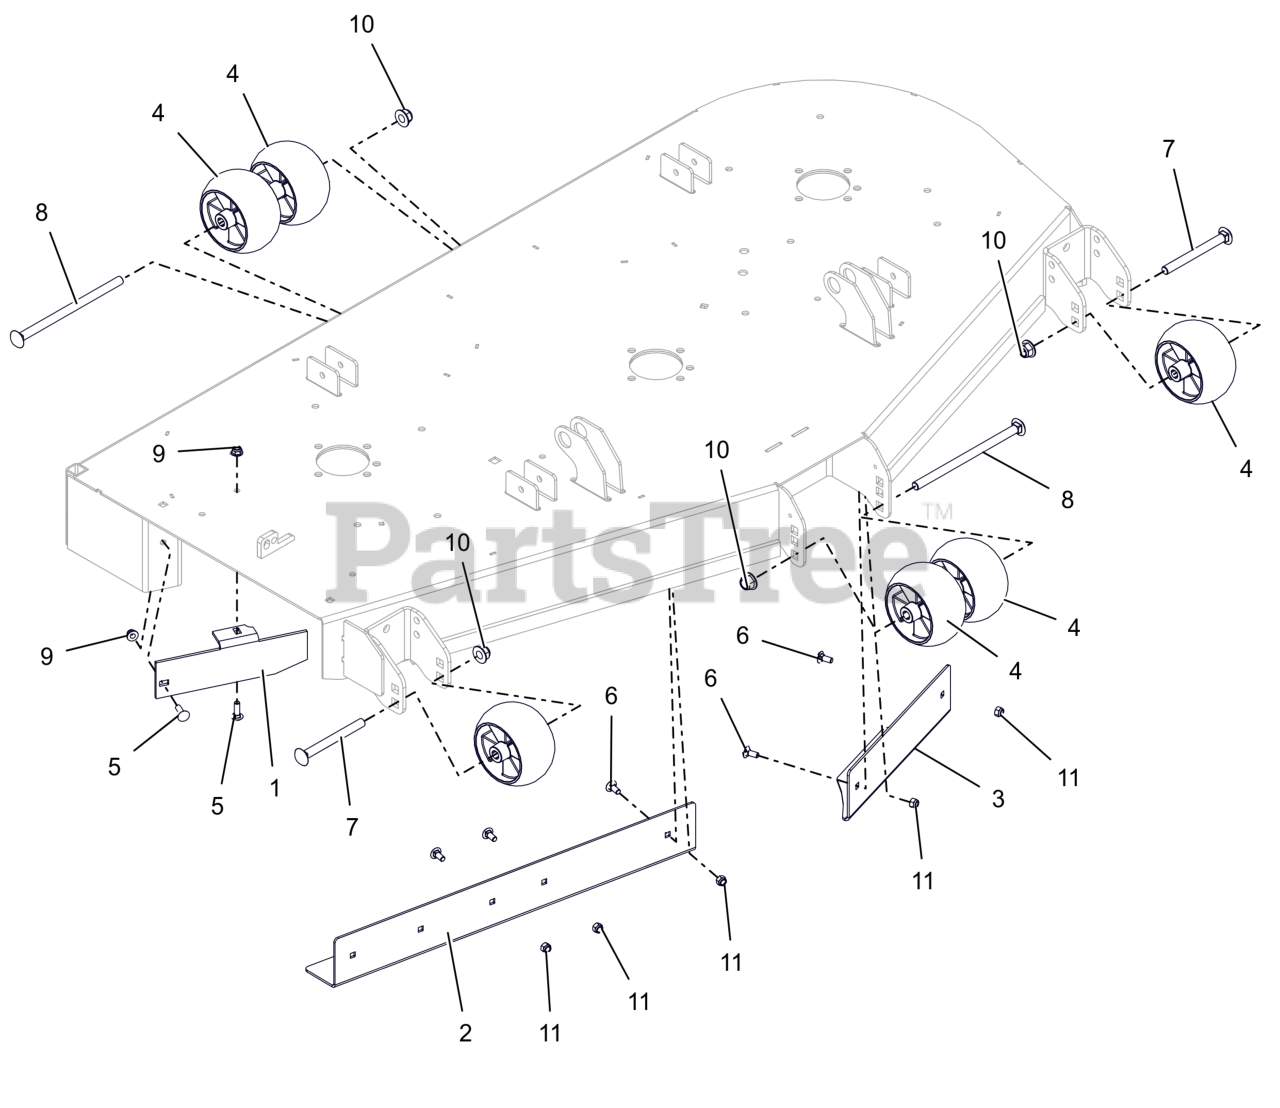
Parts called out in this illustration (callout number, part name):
1	BAFFLE, 60" DISCHARGE
2	BAFFLE, 60" RH VACUUM (ORANGE)
3	BAFFLE, 60" LH VACUUM (ORANGE)
4	WHEEL, ANTI SCALP - 5X3 CTR W/RIBS
5	BLT,RHSN .31-18X1.00 G5 ZCC
6	BLT,RHSN .31-18X.75 G5 ZCC
7	BLT, RHSN .50-13X5.00 G5 ZCC
8	BTL,RHSN .500-13 X 8.5S G5 ZCC
9	NUT,LK-NYL-FLG .31-18 G5ZC120
10	NUT,NYL-FLG .50-13 GF ZCC
11	NUT,NYL .31-18 G5 ZCC
